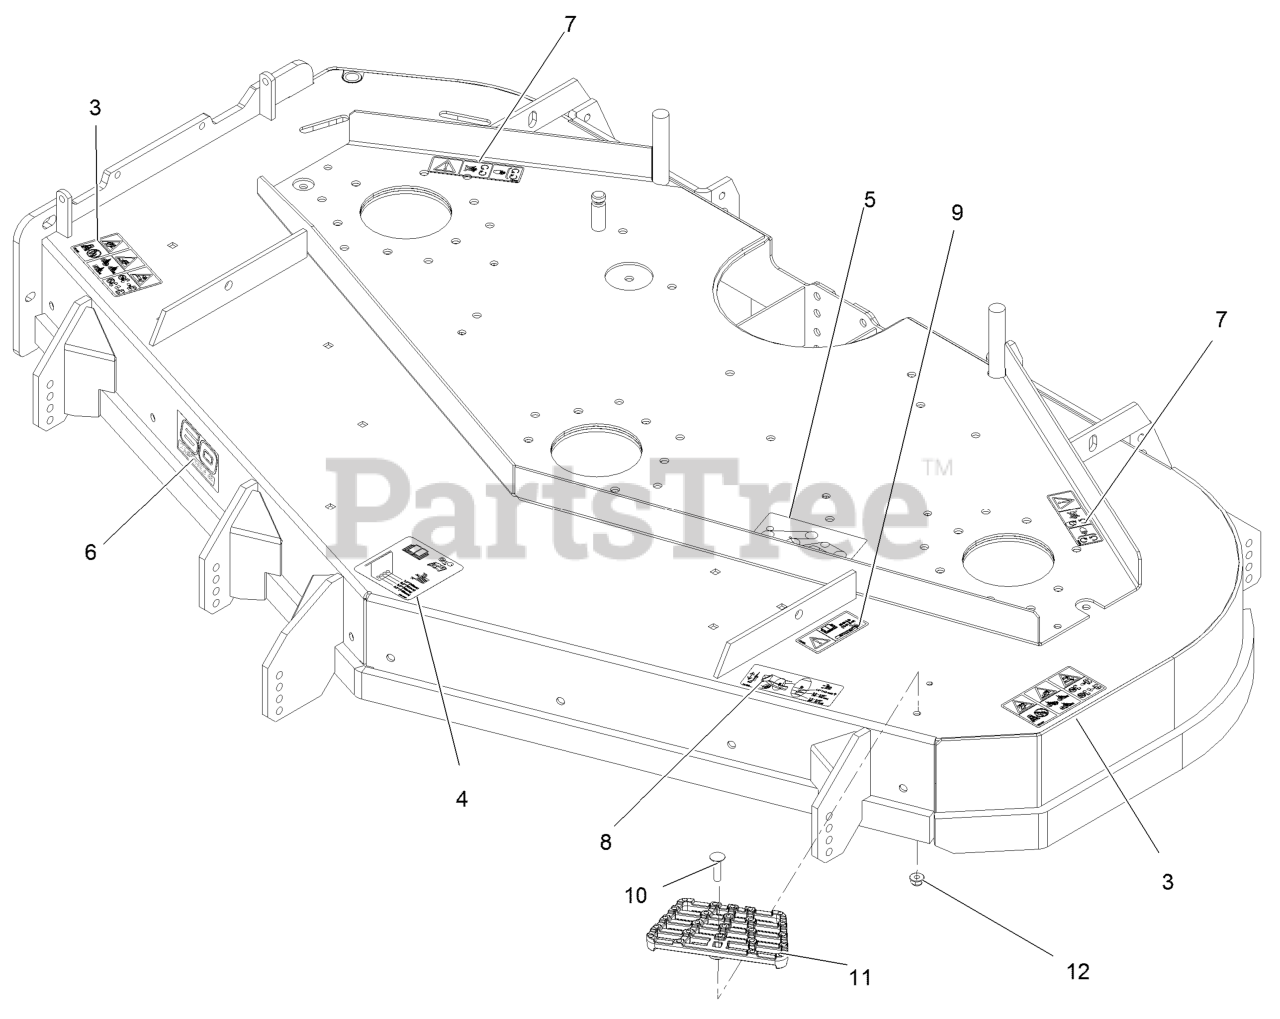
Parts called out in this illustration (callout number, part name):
3	DECAL-DANGER THROWN OBJECTS
4	DECAL-HEIGHT OF CUT
5	DECAL-BELT ROUTING
6	Decal, 605
7	DECAL-COVER, MISSING
8	DECAL-BAFFLE ADJ
9	DECAL-BOLT TORQUE
10	Bolt-Carriage 5/16-18 X 1 1/4
11	STEP-DECK
12	NUT-HF, NI
